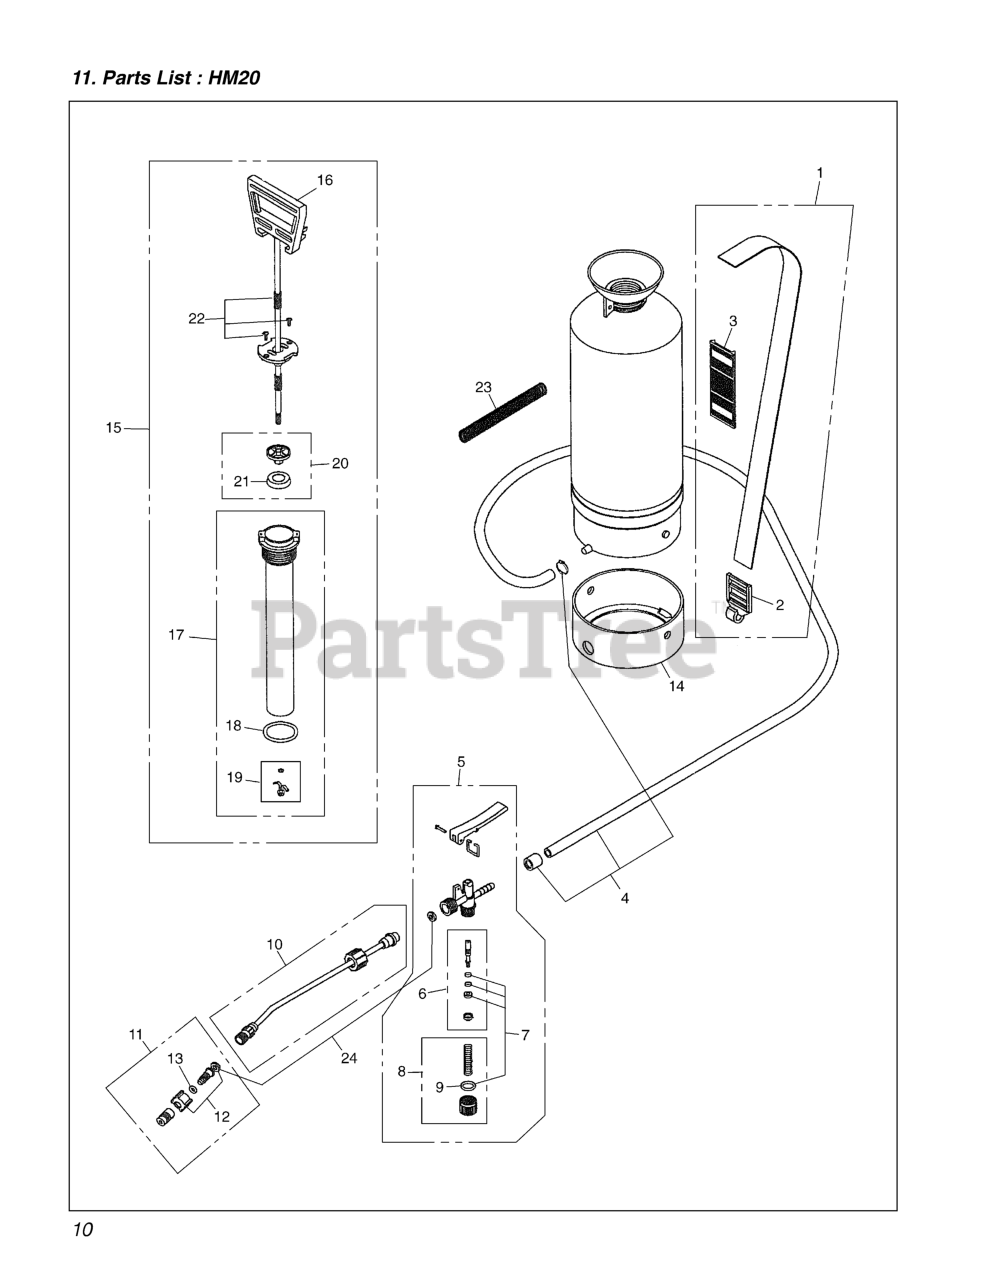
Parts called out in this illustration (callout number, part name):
1	BELT & CLIP
2	HOOK, BELT
3	PAD, SHOULDER
4	HOSE & CLAMPS
5	SPRAY PISTOL, COMP
6	SPINDLE SET
7	O-RING SET, SPINDLE
8	PLUG SET
9	O-RING SET
10	20
11	SPRAY TIP SET
12	NOZZLE HOLDER
13	O-RING, SPRAY TIP
14	BASE, COMPRESSION SPRAYER
15	PUMP MODULE, COMPLETE
16	HANDLE, PUMP
17	TUBE, PUMP
18	O-RING, PUMP
19	CHECK VALVE & O-RING
20	PLUNGER ASSY SET, PUMP
21	PLUNGER, PUMP
22	TOP SCREW SET, PUMP
23	HOSE SPRING, COMPRESSION SPRAYER
24	WASHER SET, GUN & NOZZLE
